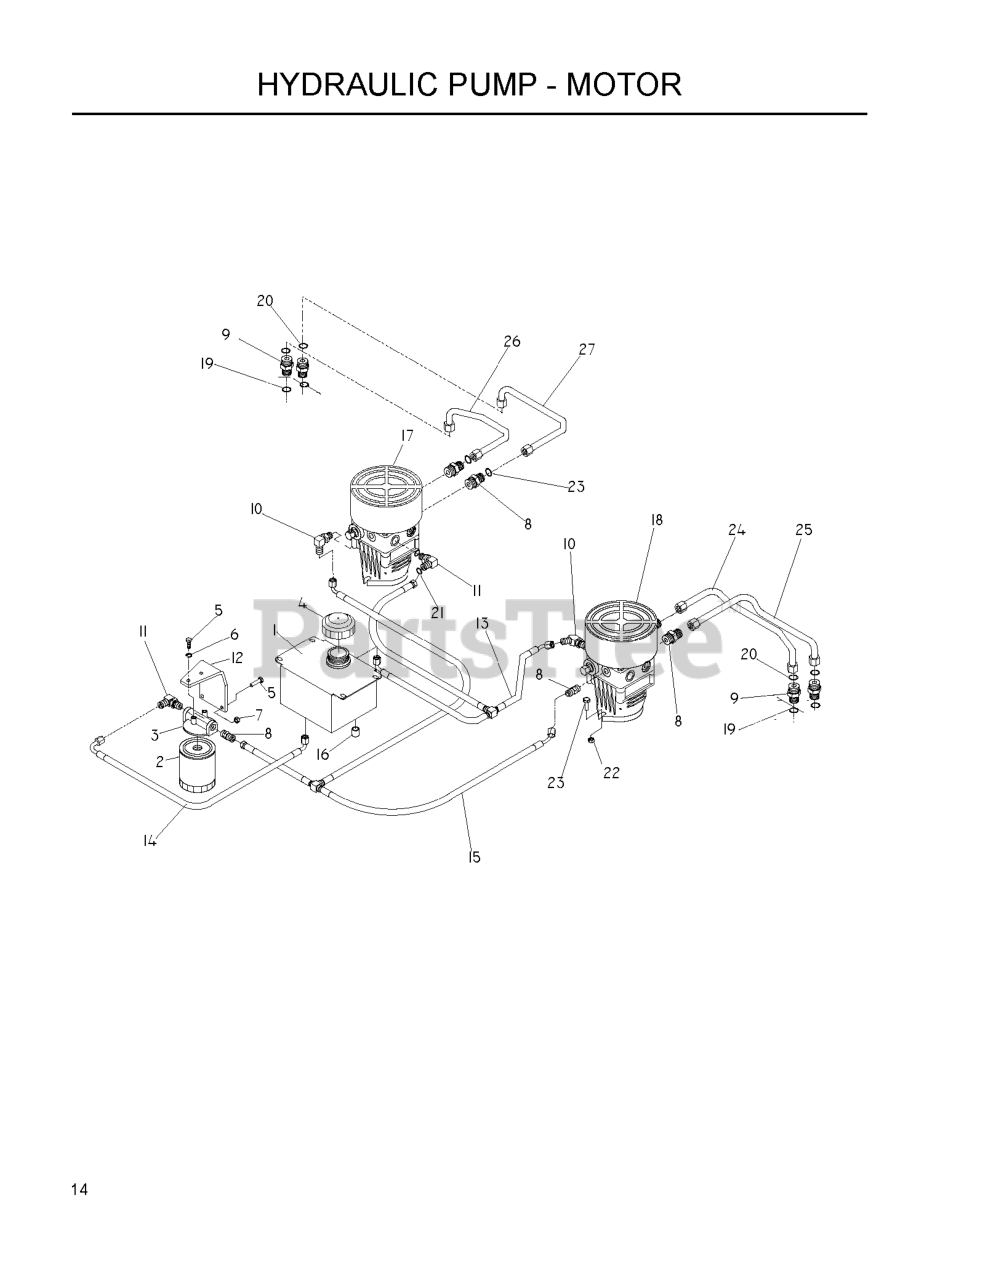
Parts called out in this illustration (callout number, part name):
2	HYDRAULIC OIL FILTER
3	FILTER HEAD
4	HYDRAULIC CAP
5	HCS 1/4C X 3/4 HCS
6	LOCKWASHER 1/4"
7	NUT.1/4-20.HEX.NYLOC.ZD
8	HYDRAULIC FITTING
10	45 DEG ADJ ELBOW
11	ELBOW, F6801-6-6-0 90 DEGREE
12	OIL FILTER BRKT
13	HOSE, T-ASM RETURN
14	HOSE, TANK - FILTER LINE
15	HOSE, T-ASM SUPPLY
16	NUT 9/16-18 JIC CAP
17	HG_PUMP, 10CC W/FAN RIGHT
18	HG_PUMP, 10CC W/FAN LEFT
22	NUT 3/8C CENTERBLOCK
23	4CS 3/8C X 1 SERRATED HEAD
24	HOSE, RPA - MA LINE
25	HOSE, RPB - MB LINE
26	HOSE, LPA - MB LINE
27	HOSE, LPB - MA LINE
